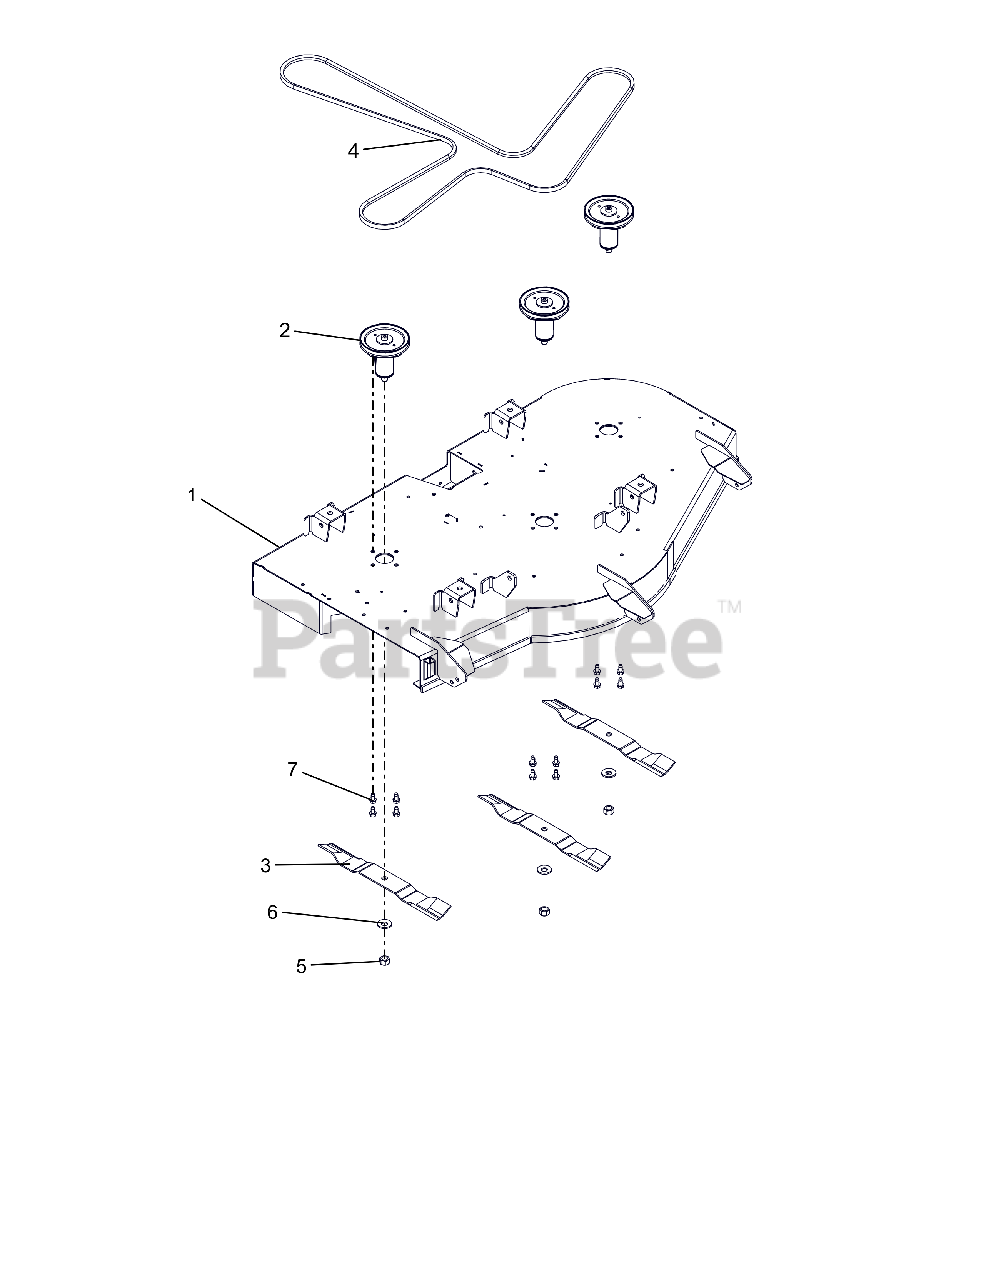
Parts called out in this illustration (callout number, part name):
1	KIT, 52" ARIENS DECK W/DECALS
2	KIT, DECK SPINDLE ASM-52
3	BLADE, 18" - 30 DEG .5 OFFSET
4	V-BELT, HA-WRAPPED
5	NUT-STD .625-18 ZCC
6	WSHR-BLVL .669X1.535X.138
7	SCR,TAP .375-16X.75 HWH TR ZCC
